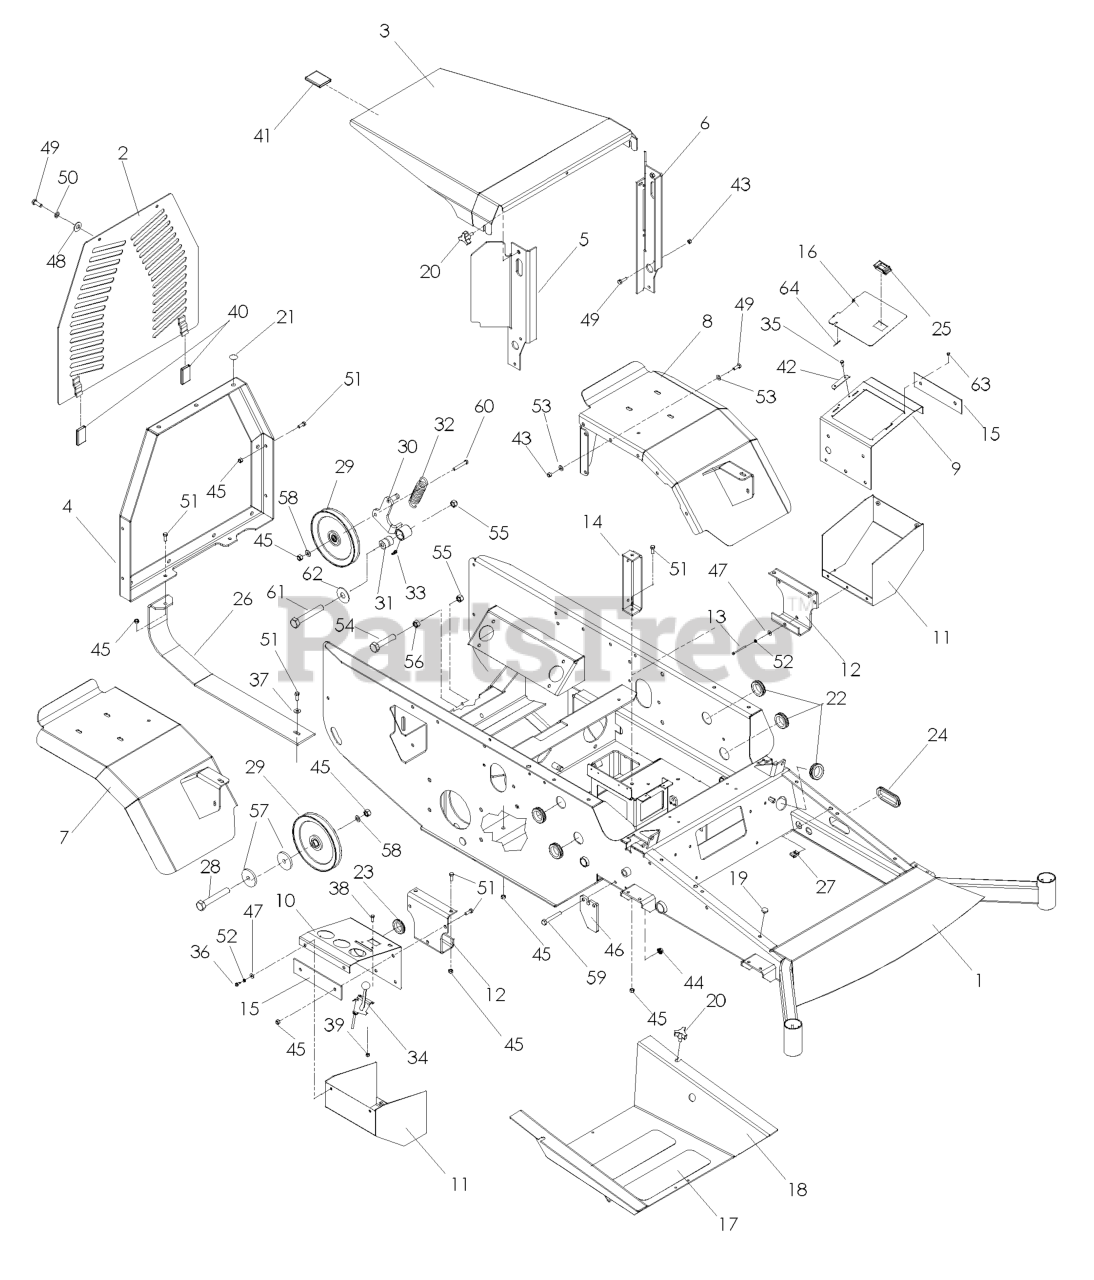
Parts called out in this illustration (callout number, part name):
1	FRAME W/DECALS
2	BACK PANEL
3	HOOD ORANGE
4	REAR FRAME
5	SUPPORT WLDMT, RT
6	SUPPORT WLDMT, LT
7	FENDER WELDMT, RH
8	FENDER WELDMT, LH
9	CONSOLE TOP-FINISHED ORANGE
10	CONTROL PANEL
11	CONSOLE BOTTOM
12	CONSOLE SUPPORT
13	HCS 1/4-20 X 3 GR 5 ZD
14	SUPPORT WELDMENT
15	BLACK-STIFFNER-PAINTED
16	DOOR - FINISHED
17	ANTI-SKID PAD
18	FOOT PLATE WIDMT
19	GROMMET, BUMPER
20	KNOB W/STUD
21	GROMMET BUMPER
26	SKID PLATE
27	U-CLIP 5/16-18 NUT RETAINER
28	HCS 3/8C X 2 1/2
30	ARM WELDMENT
33	ZERK
34	THROTTLE CONTROL W/BALL KNOB
35	SCR #10-12X3/4 HEX WAS HD ZD
36	SCREW 1/4 X 5/8
37	WASHER 3/8 FLAT
38	HCS #10-24 X 1/2
39	NUT 10-24 NYLOC
43	NUT 5/16 NYLOC
44	NUT 5/16C WHIZ
45	NUT 3/8-16 NYLOC
47	WASHER 1/4 FLAT
48	WASHER 5/16 FLAT
49	HCS 5/16C X 1
50	WASHER.LOCK.HVY.HLCL.SPR.5/16
51	HCS 3/8-16X1.GRD.5.ZD
52	LOCKWASHER 1/4"
53	FLAT WASHER 5/16 SAE
54	HCS 1/2-13X2 GR 8
55	NUT 1/2-13 HEX NYLOC ZD
56	NUT HEX 1/2
57	SPINDLE WASHER
58	WASHER 3/8 SAE FLAT
60	HCS 3/8C X 2 1/4
61	HEX SCREW 1/2-13 X 2.5" GR 5
62	WASHER 1/2 FLAT
64	FOAM STRIP
